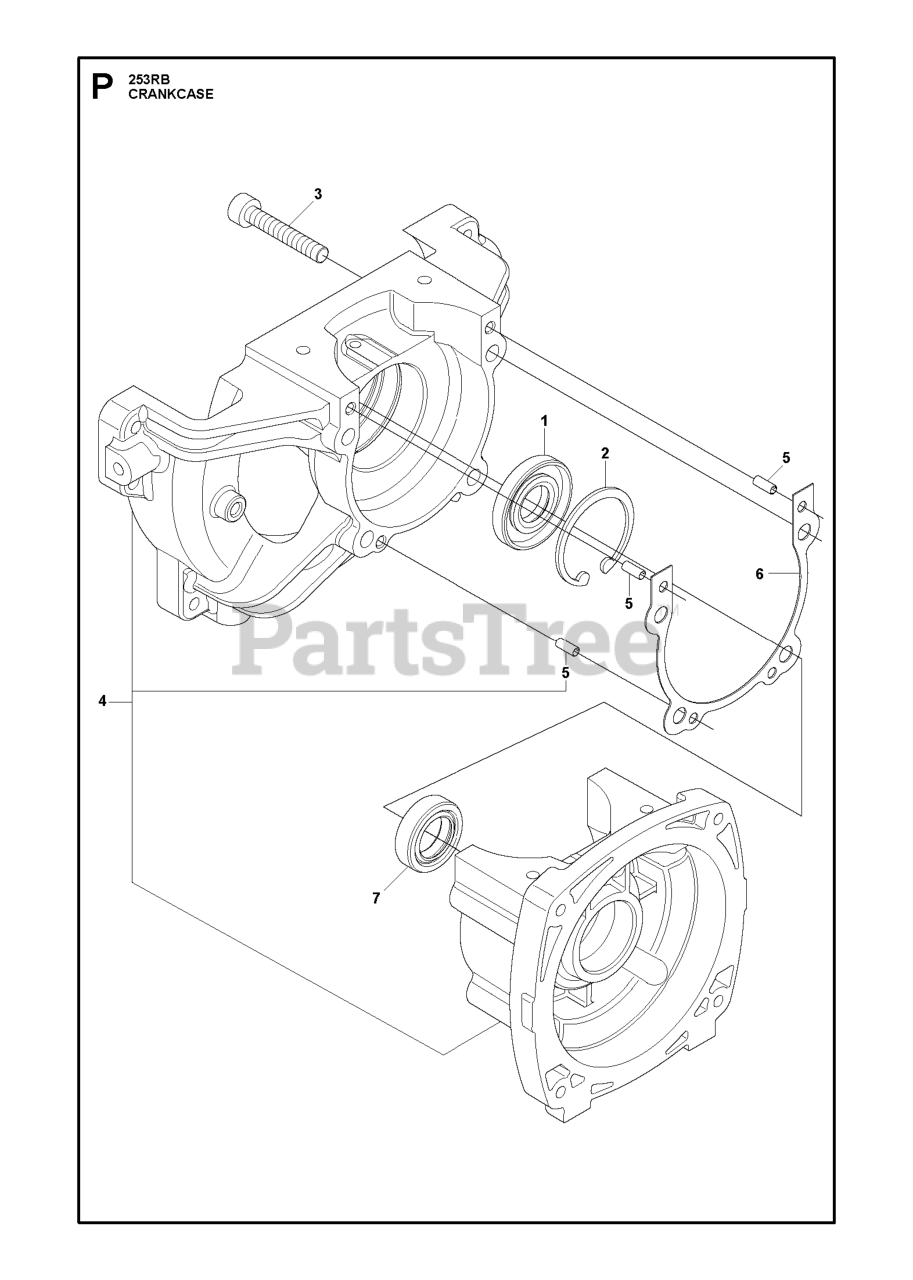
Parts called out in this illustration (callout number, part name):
3	BOLT
4	CRANKCASE COMP
6	GASKET, CASE
